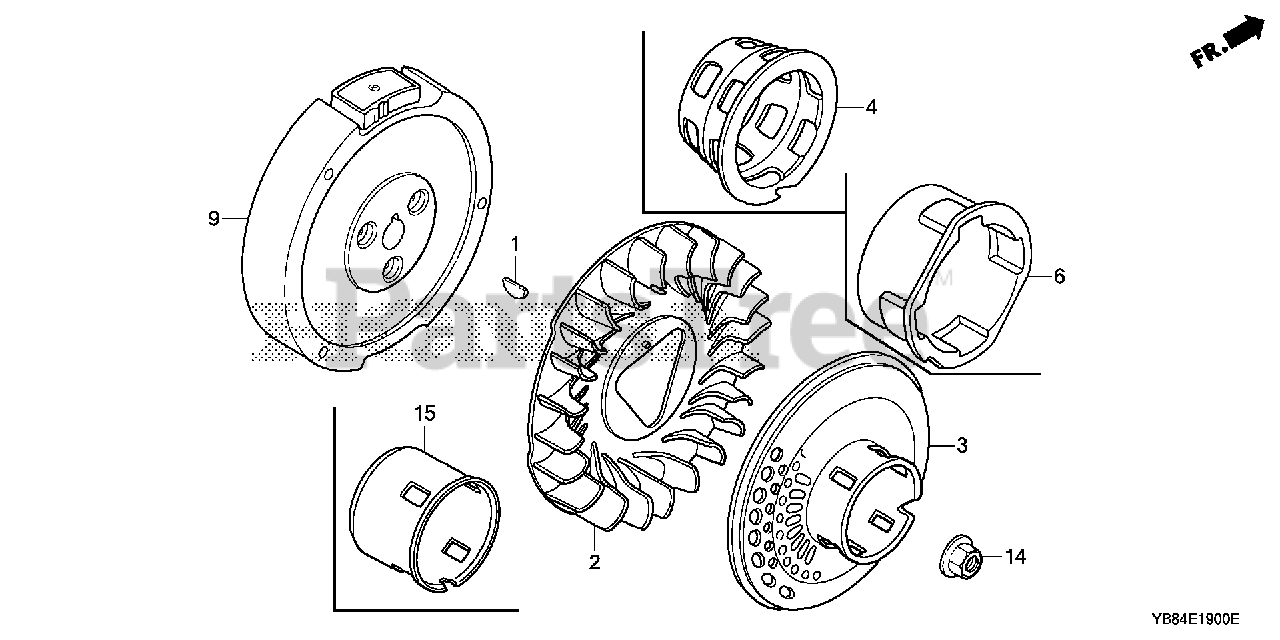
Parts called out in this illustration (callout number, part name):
1	KEY, SPECIAL WOODRUFF (25X18)
2	FAN, COOLING
3	PULLEY, STARTER (SCREEN GRID)
14	NUT, SPECIAL (16MM)
